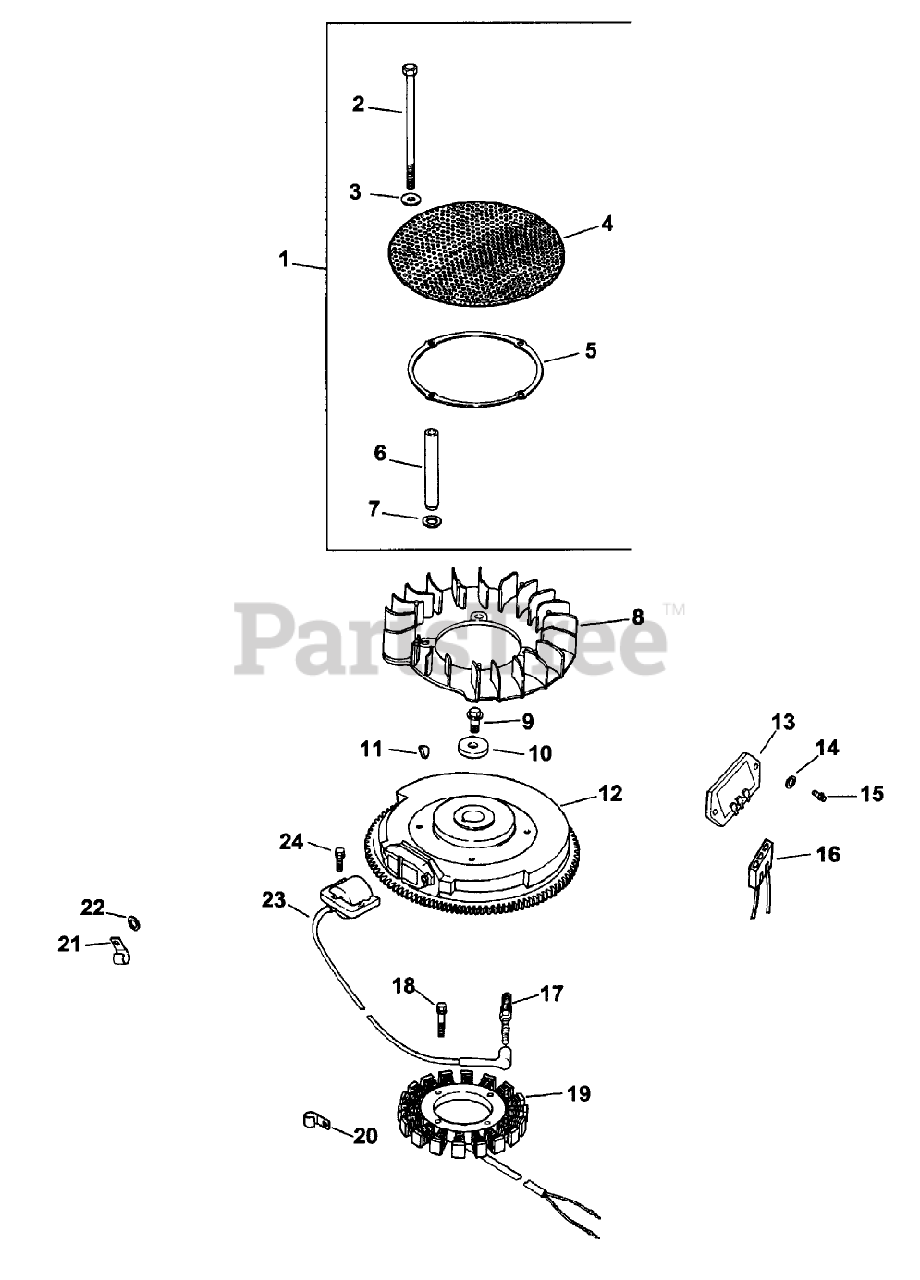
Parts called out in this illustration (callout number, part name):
1	Kit, chopper screen (Includes 2-7)
2	Screw-Hex
3	Washer
4	Screen-Grass
5	Ring-Support
6	Spacer
7	Washer, sping
8	Fan
9	Screw
10	Washer
11	Key
12	Flywheel
13	Rectifier-Regulator
14	Washer
15	Screw
16	Connector
17	Plug-Spark
18	Screw
19	Kit, 15 amp stator (Includes Bracket, stator wire 24 126 71)
20	Clip
21	Clip
22	Washer
23	Module-Ignition
24	Screw
